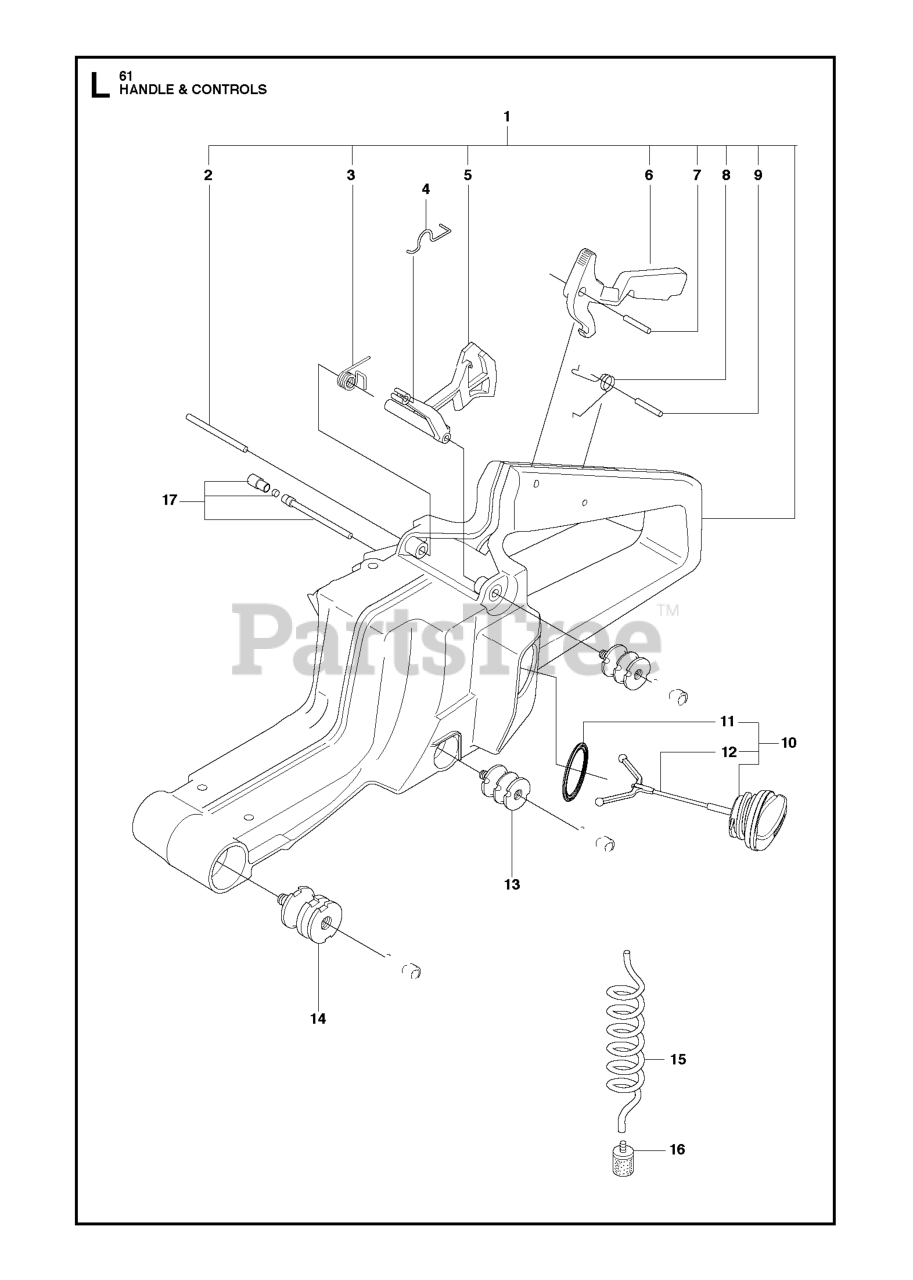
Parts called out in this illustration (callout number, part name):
1	TANK UNIT CPL
4	THROTTLE ROD
6	THROTTLE CATCH
7	SPRING PIN 3X24
9	SPRING PIN 3X24
13	ANTIVIBE ELEMENT
14	ANTIVIBE ELEMENT
15	FUEL HOSE
16	RP FUEL FILTER
